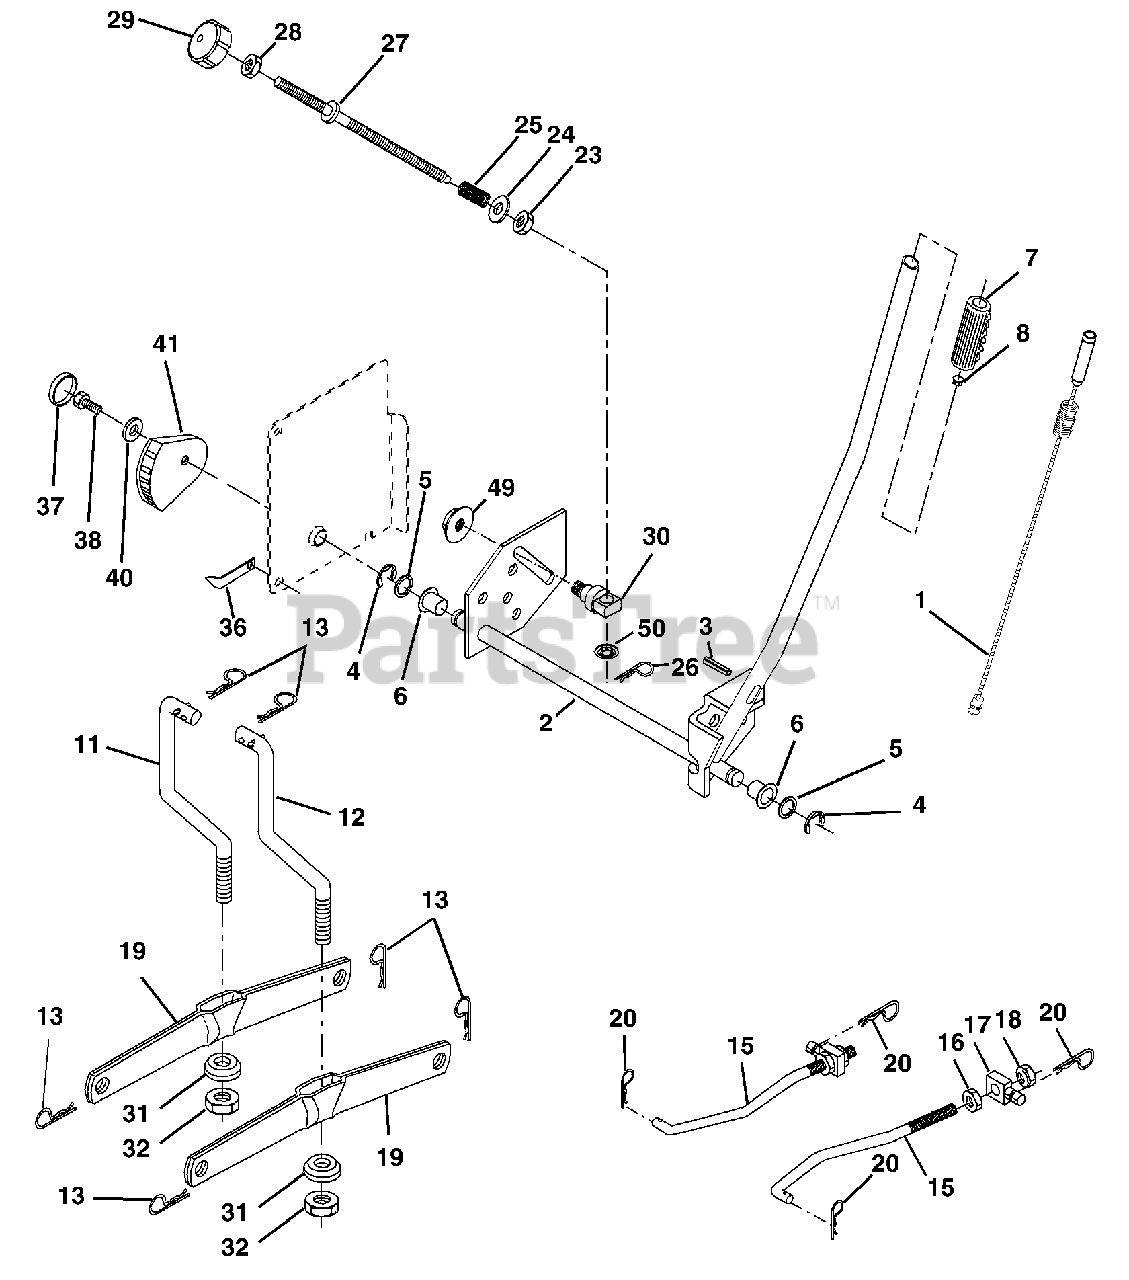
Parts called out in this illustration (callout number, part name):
1	Wire Asm Inner/Sprg W/plunger
2	Shaft Asm Lift RH w/Inf
3	Pin Groove
4	E Ring #5133-62
5	Washer 21/32 x 1 x 21 Ga.
6	Bearing Nylon Blk 629 Id
7	Grip Handle
8	Button Plunger
11	Link Lift LH Fixed Length
12	Link Lift RH Fixed Length
13	Retainer Spring
15	Link Front
16	Nut Jam Hex 1/2-13 unc
17	Trunnion
18	Nut Lock W/Wsh 1/2-13 unc
19	Arm Suspension Rear
20	Retainer Spring
23	Nut Special
24	Washer 13/32 x 5/8 x 16 Ga.
25	Spring 2-1/8"
26	Retainer Clip
27	Rod Adj Lift Zinc 7.49 Wrk Lg
28	Nut Hex Jam 3/8-16 unc
29	Knob Inf 3/8-16 unc Blk W/sym
30	Trunnion Infin Height
31	Bearing Pvt Lift
32	Nut Crownlock 3/8 - 24
36	Pointer Height Indicator
37	Plug Hole Blk 1.485/1.515 Dia.
38	Screw 5/16-18 x 1
40	Washer 11/32 x 1-1/2 10 Ga.
41	Indicator Height STLT
49	Nut Hex Flange Lock
50	Nut PUsh Phos & Oi
